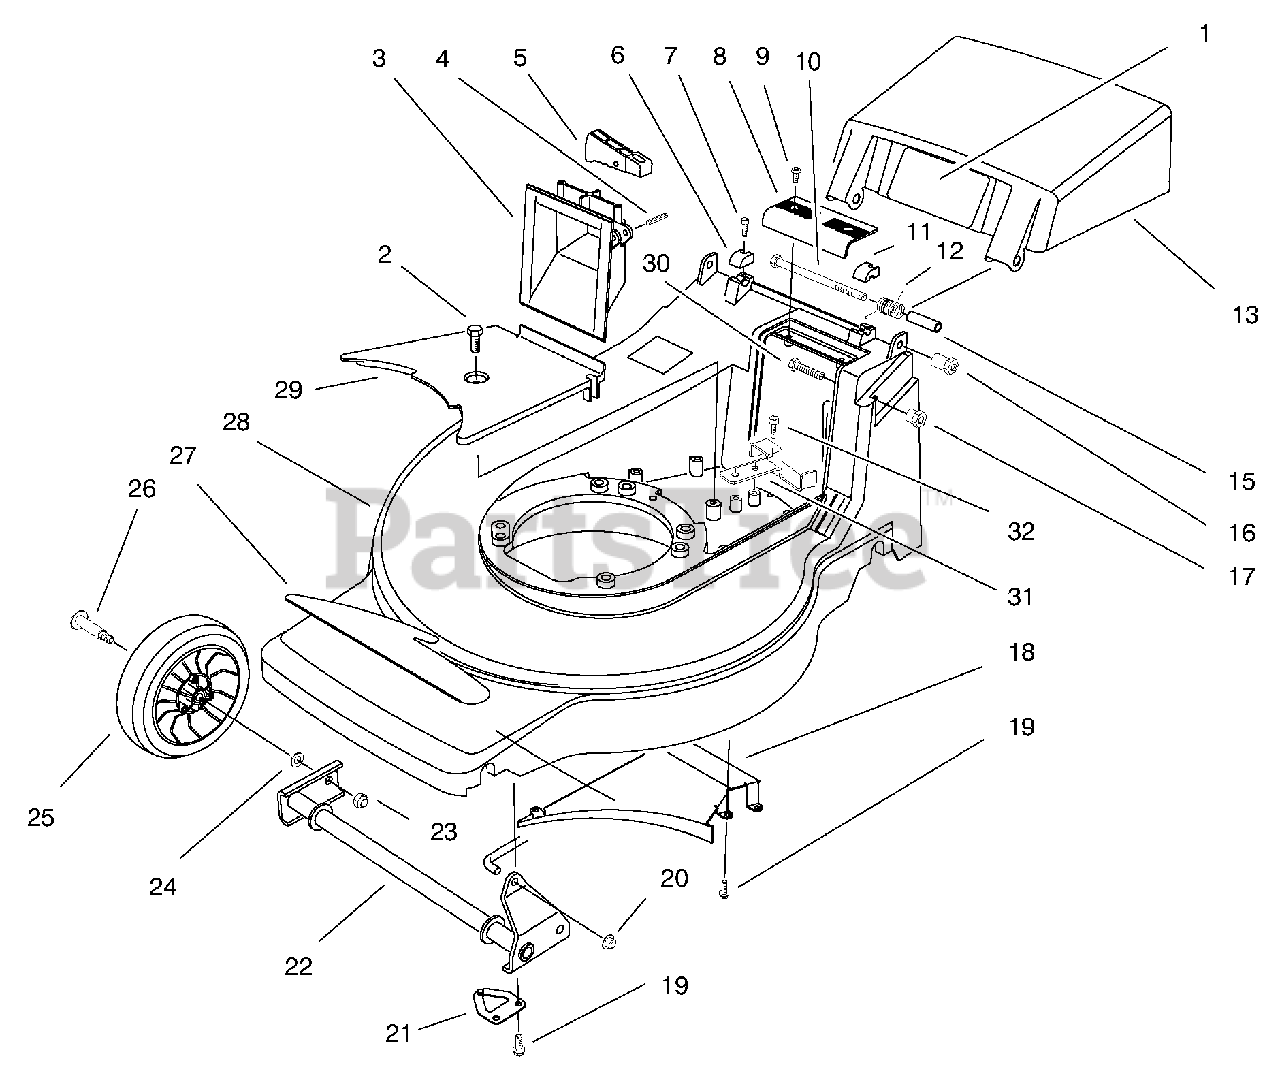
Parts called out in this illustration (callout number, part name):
1	Decal-Danger
2	Screw-Tapping
3	Grip-Lower
4	Pin-Groove
5	Trigger-HOC
6	Cap-R.H. Hinge Bolt
7	Screw-Thread Forming
8	Grip-Upper
9	Screw-Pan Hd. Phillips
10	Screw-Hex Hd. Cap
11	Cap-L.H. Hinge Bolt
12	Spring-Door
13	Door-Discharge (Incl. Ref. # 1)
15	Spacer-Door
16	Spacer-Handle
17	Spacer-Handle
18	Ramp-Discharge
19	Screw-Tapping
20	Nut-Push
21	Retainer-Shaft
22	Pivot-Front
23	Nut-Lock
25	Wheel & Tire Assembly
26	Bolt-Wheel
27	Decal-Deck 400XP
29	Cover-Belt
30	Screw-Hex Hd. Cap
31	Guide-Belt Rear
32	Screw-HH
